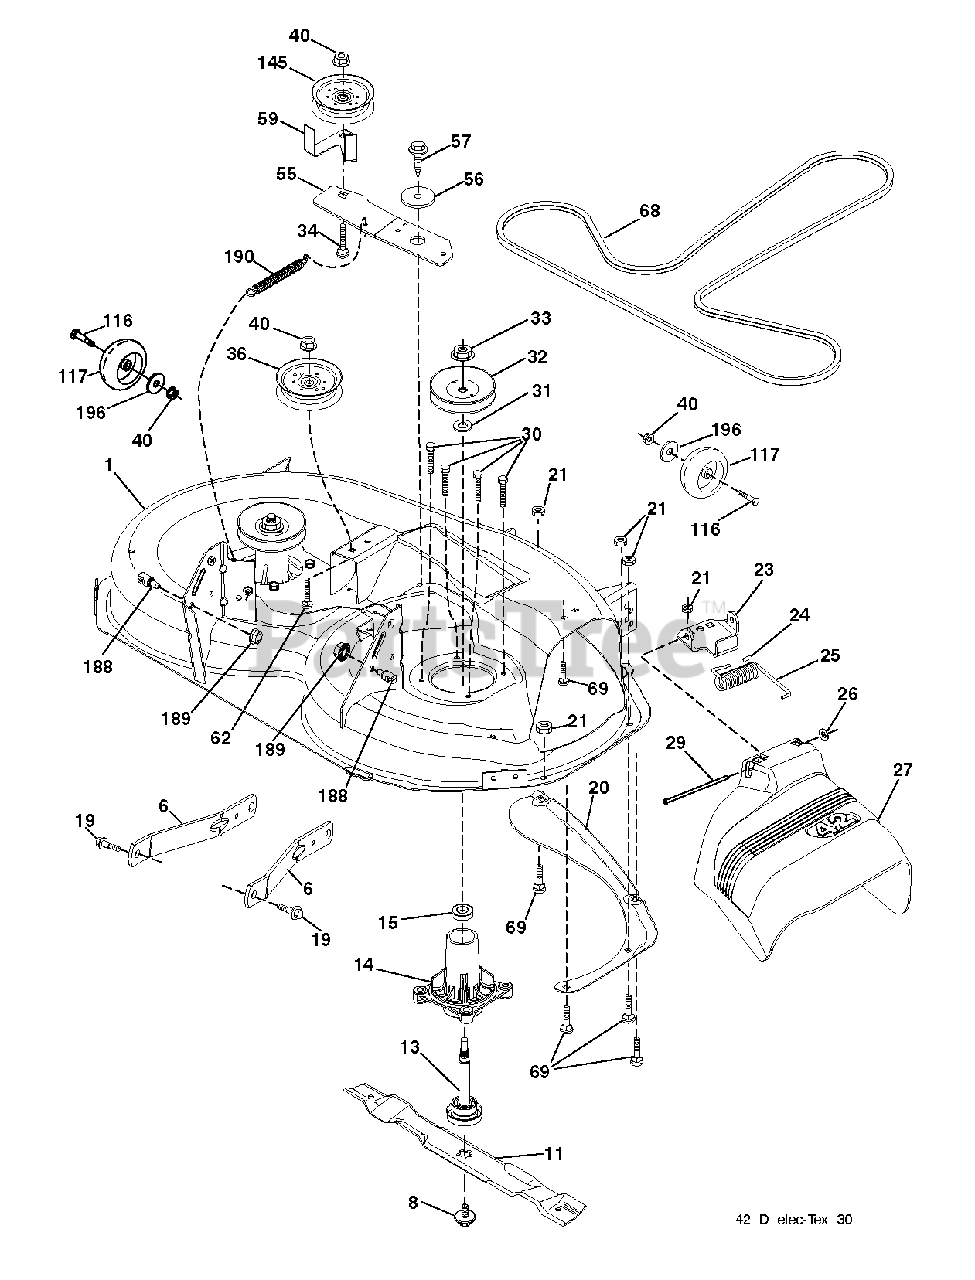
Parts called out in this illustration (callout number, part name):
1	DECK.WELDMENT.42"
6	ARM.SUSPENSION.MOWER.R
8	BOLT.WASHER.ASM.7/16-2
11	42" HI-LIFT BLADE
13	SHAFT.ASM.MDRL.N/GREASE.38
14	HOUSING.MANDREL.4PT.
19	BOLT.SHOULDER
20	BAFFLE.VORTEX
21	LOCKNUT
23	BRKT.DEFLECTOR.38"2005+
24	CAP-SLEEVE LT
25	SPRING.TORSION.DEFLECT
26	NUT PUSH M
27	SHIELD.DEFLECTOR.MOWER.42"BLAC
29	ROD.HINGE
30	SCREW, WASHER HEAD
31	WASHER.SPACER.MANDREL
32	PULLEY/MANDREL
33	NUT.FLANGE.LOCK.TOP
34	BOLT.3/8-16X1.50
36	PULLEY.IDLER.2006
40	NUT LOCK FLG 3/8-16 UNC
55	IDLER.ARM.42"
56	SPACER.RETAINER
57	SCREW 3/8-16X1
59	GUARD, BELT
68	BELT V SECONDARY
69	BOLT
116	BOLT M
117	WHEEL.GAGE.HALF.SPOKED
145	PULLEY.IDLER.48"PRIMARY
188	STUD.FASTNER.W/ANTI-ROTATE
189	NUT LOCK HEX FLANGE 5/16-18
190	SPRING.MOWER.DRIVE.ELECTRIC
196	WASHER
